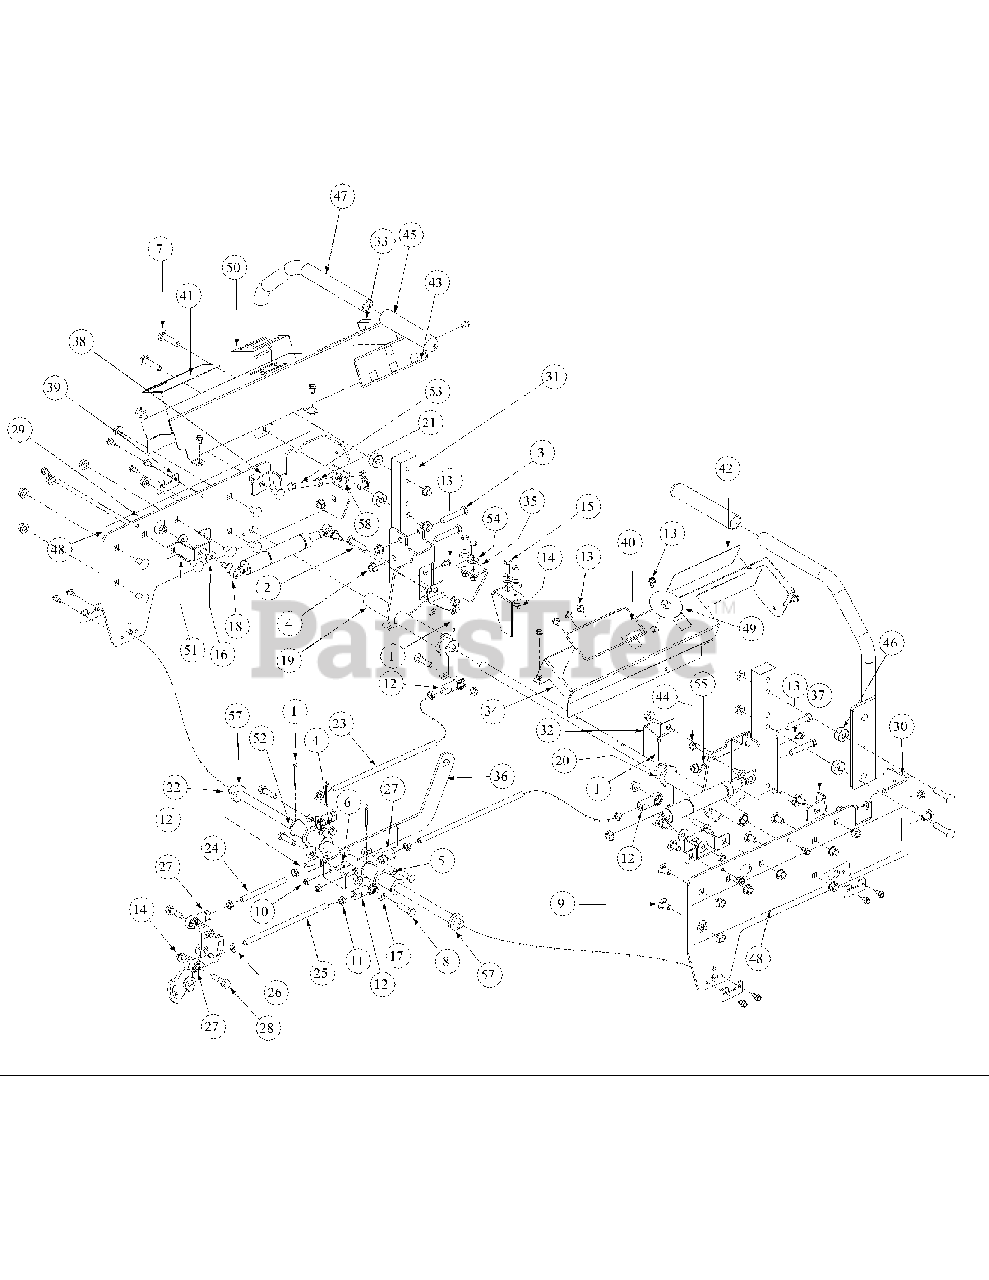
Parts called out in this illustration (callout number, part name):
1	Cotter Pin .125 Dia x 1.0
2	Hex Cap Screw, 3/8-16, 1.50
3	Hex Cap Screw, 3/8-16, 2.5
4	Hex Nut, 3/8-16, Lock Flange
5	Grease Fitting, 1/4-28 x 3/16
6	Hex Cap Screw, 1/4-20,.75
7	Hex Carriage Screw, 3/8-16 x 2
8	Hex Cap Screw, 3/8-16, 1.25
9	Carriage Bolt, 3/8-16 x .75
10	Lock Hex Nut, 1/4-20
11	Hex Jam Nut, 3/8-24
12	B/Joint, 3/8-24, Right Hand Female
13	Screw, TT, 1/4-20, 0.5, Hex Index Washer
14	Nut, Lock, Hex Flange, 5/16-18
15	Hex, Cap Screw, 5/16-18 x 3/4
16	Belle Washer, .325 x .930 x .045
17	Belle Crank Assembly,
17	Bushing
18	Cylinder Return to Neutral
19	Hub Assy, Control LH Bearing
20	Hub Assy, Control RH Bearing
21	Nut, 3/8-16, Jam
22	Shaft Mounting Belle Crank
23	Rod Connector 3/8 OD x 10.125
24	Rod Connector, 3/8 OD x 4.28 LG LH
25	Rod Connector, 3/8 OD x 8.06 LG RH
26	Nut, 3/8-24, Jam, LH Third
27	B/Joint, 3/8-24, LH Female
28	Screw, Shoulder Control Rod
29	Side Panel, Control, Left
30	Side Panel, Control, Right
31	Mounting Handle
32	Lever, Safety Switch
33	Control Panel, LH
34	Control Panel, RH
35	Switch Mounting Bracket, Lapbar
36	Link Mounting Control Shaft, Bracket
39	Holder Shaft, Park Brake
40	Decal , Right Hand Console
41	Decal, Left Hand Console
42	Decal Right Hand Control
43	Decal, Left Hand Control
44	Nut, Hex, Center Lock, M8 x 1.2
46	Spacer, .406 ID x 1.00 OD x .38
47	Lapbar Handle, One Position
48	Side Label, CCC
49	Label, Ignition, 2.5 Diameter
50	Label, Control, Throttle and Choke
51	Bracket Assembly, Mount Dampener
52	Flat Washer, 5/8 Nylon
53	HHCS, 3/8-16, 3.00
54	Flat Washer, 5/16
55	Grease Fitting, 90°, 1/4-28
57	Shaft Collar, .625 ID, 1.00 OD, .438 Lg
58	U-Nut, 3/8-16 x .75
